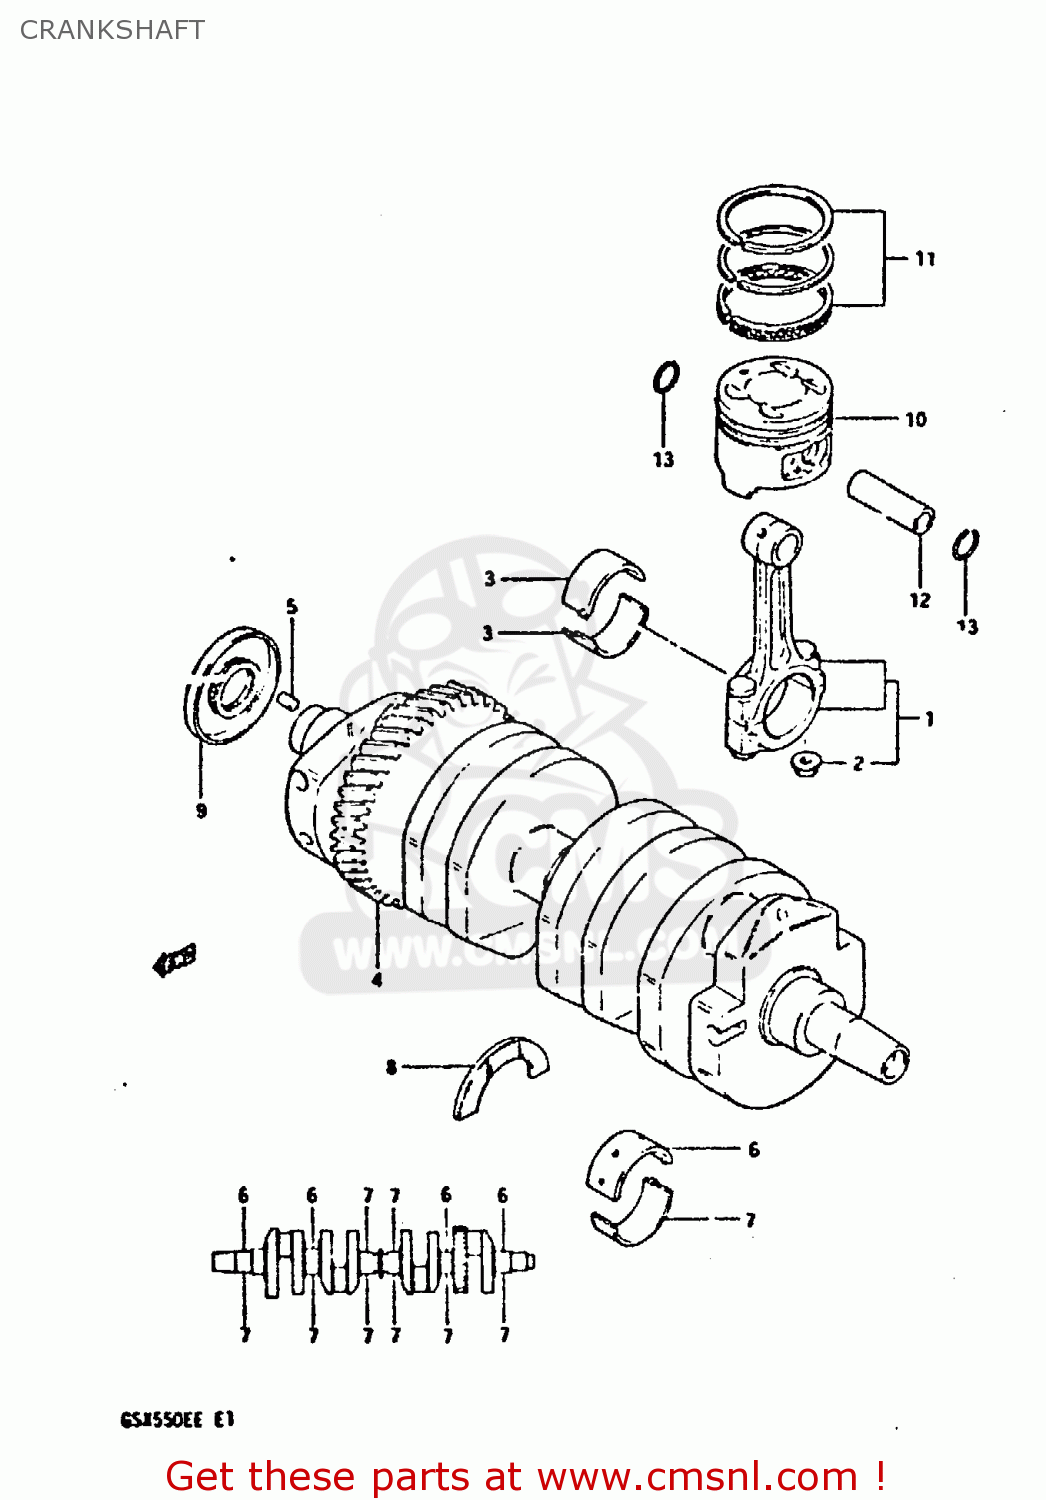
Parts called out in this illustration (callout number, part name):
1	ROD ASSEMBLY,CONNECTING
2	NUT
3	BEARING,CRANK PIN
4	CRANKSHAFT ASSEMBLY
5	PIN
6	BEARING,CRANKSHAFT
7	METAL CRANKSHAFT
8	PLATE,CRANK THRUST
9	OIL SEAL
10	PISTON
11	RING SET,PISTON
12	PIN,PISTON
13	CIRCLIP
